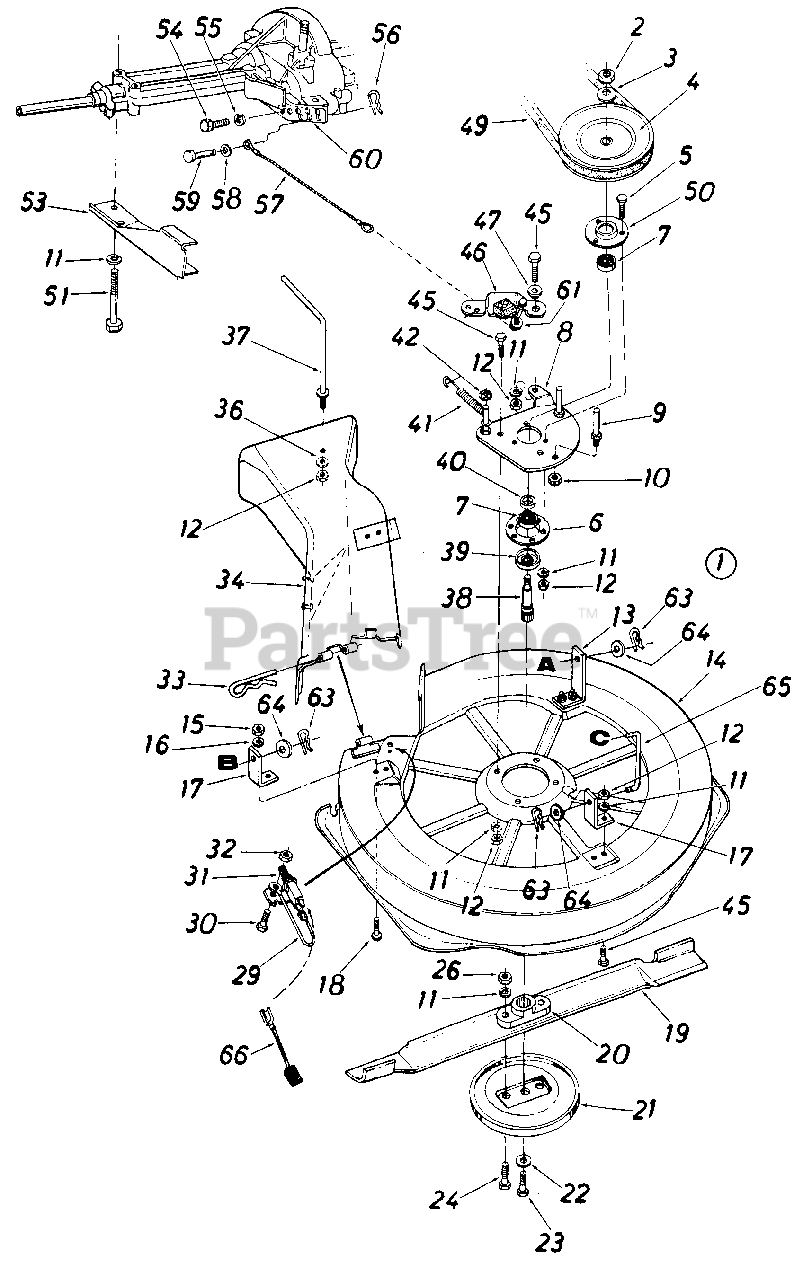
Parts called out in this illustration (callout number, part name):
1	30" R.D. Deck Ass'y. Comp.
2	Hex Jam Nut 5/8-18 Thd.
3	Bell-Wash. .630" I.D. x 1.25"
4	5/8 V-Pulley .75" I.D. x .7"
5	Hex Sems 5/16-18 x .62" Lg.*
6	Brg. Housing 1.85" I.D.
7	Ball Brg.....787" I.D.
8	Spindle Mtg. Plate
9	Stud 3/8-16 x 2.75" Lg.
10	Hex Jam Nut 3/8-16 Thd.
11	L-Wash. 5/16" I.D.*
12	Hex L-Nut 5/16-18 Thd.
13	Hanger Brkt. 2.92"
17	Hanger Brkt. 1.92"
18	Truss Mach. Scr. 5/16-18 x .75" Lg.*
19	30" High Lift Blade
20	Blade Adapter
21	Scalp Plate
22	L-Wash. 3/8" I.D.*
23	Hex Bolt 3/8-24 x 1.0*
24	Hex Bolt 5/16-24 x 1.0" Lg.
26	Hex Nut 5/16-24 Thd.*
29	Electrical Wire
30	Hex Bolt 1/4-20 x .50" Lg.*
31	Safety Switch
32	Hex Nut 1/4-20 Thd.*
33	Internal Cotter Pin
34	R.D. Chute Deflector
36	L-Wash. .32" I.D. x .62" O.D.
37	90ø Rod 5/16-18 Thd.
38	Blade Spindle 5.20
39	Bearing Shield
41	Extension Spring
42	Push Speed Nut
45	Hex Bolt 5/16-18 x .75"*
46	Blade Brake Brkt. Ass'y.
47	Shoulder Spacer .500" Dia.
49	"V"-Belt 1/2" x 52" Lg.
50	Open Brg. Housing
51	Hex Bolt 5/16-18 x 2.75"
53	Lower Outside Belt Guard
54	Hex Bolt 1/4-20 x .62" Lg.*
55	L-Wash. 1/4" I.D.
56	Int. Cot. Pin 5/16" Dia.
57	Brake Cable 11.75" Lg.
58	Fl-Wash. .281" I.D. x .50"
59	Clevis Pin 1/4" Dia.
60	Lower Inside Belt Guard
61	Cap Speed Nut 1/4" Rod
63	Int. Cotter Pin 1/2" Dia.
64	Fl-Wash. .531" I.D. x .930"
65	Deck Link 3.9" Lg.
